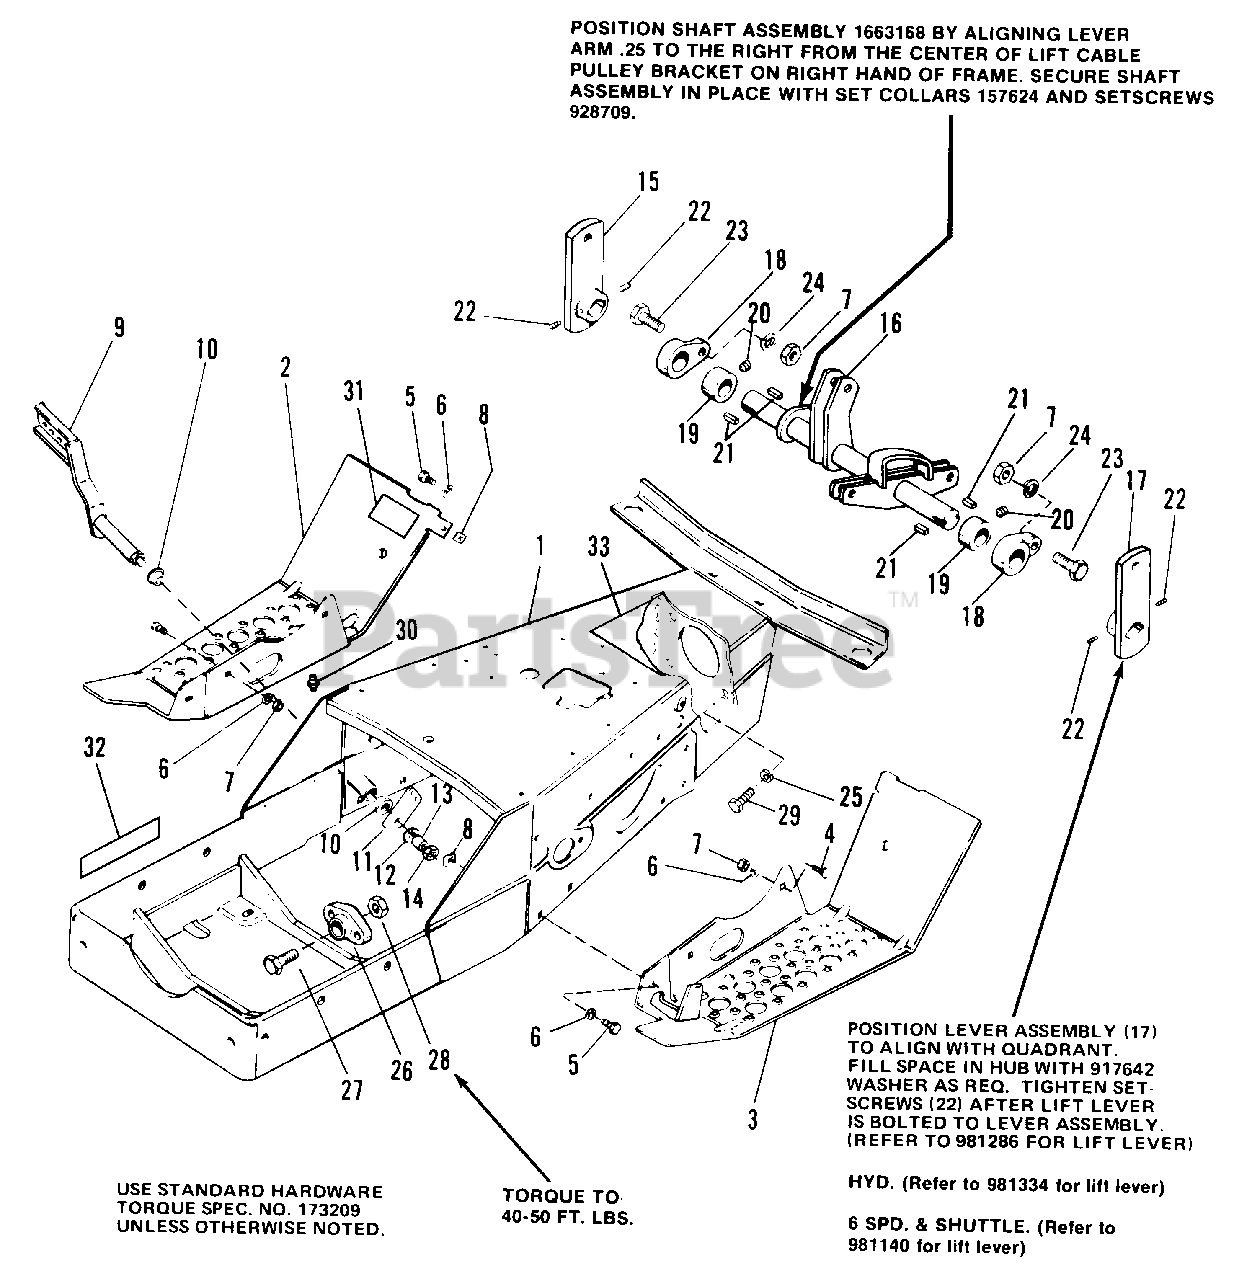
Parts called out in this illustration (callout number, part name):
1	REAR FRAME ASSEMBLY
2	FOOT REST, R.H.
3	FOOT REST, L.H.
4	BOLT, Carriage, 5/16-18 x 3/4
5	CAPSCREW, Hex Hd., 5/16-18 x 3/4
6	LOCKWASHER, 5/16
7	NUT, Hex, Full, 5/16-18
8	NUT, Speed, Tinn., 5/16-18
9	FOOT PEDAL ASSEMBLY
11	ARM, Pedal Foot
12	WASHER, 3/8
13	LOCKWASHER, 3/8
14	NUT, Hex, Full, 3/8-16
15	FRONT LIFT LEVER ASSEMBLY
16	LIFT SHAFT ASSEMBLY
17	LIFT LEVER ASSEMBLY
18	BEARING, Lift Lever
19	SET, Collar
20	SETSCREW, Cup Pt., 5/16-18 x 3/8
22	SETSCREW, Soc. Hd., 5/16-18 x 1/4
23	CAPSCREW, Hex Hd., 5/16-18 x 1-1/4
24	LOCKWASHER, 5/16
25	LOCKWASHER, 7/16
26	BEARING, Pivot
27	CAPSCREW, Whix, 3/8-16 x 1-1/4
28	NUT, Flange, 3/8-16
29	CAPSCREW, Hex Hd., 7/16-14 x 1-1/2
30	LUBE FITTING
31	DECAL, Parking Brake
32	DECAL, Clutch
33	DECAL, Safety
